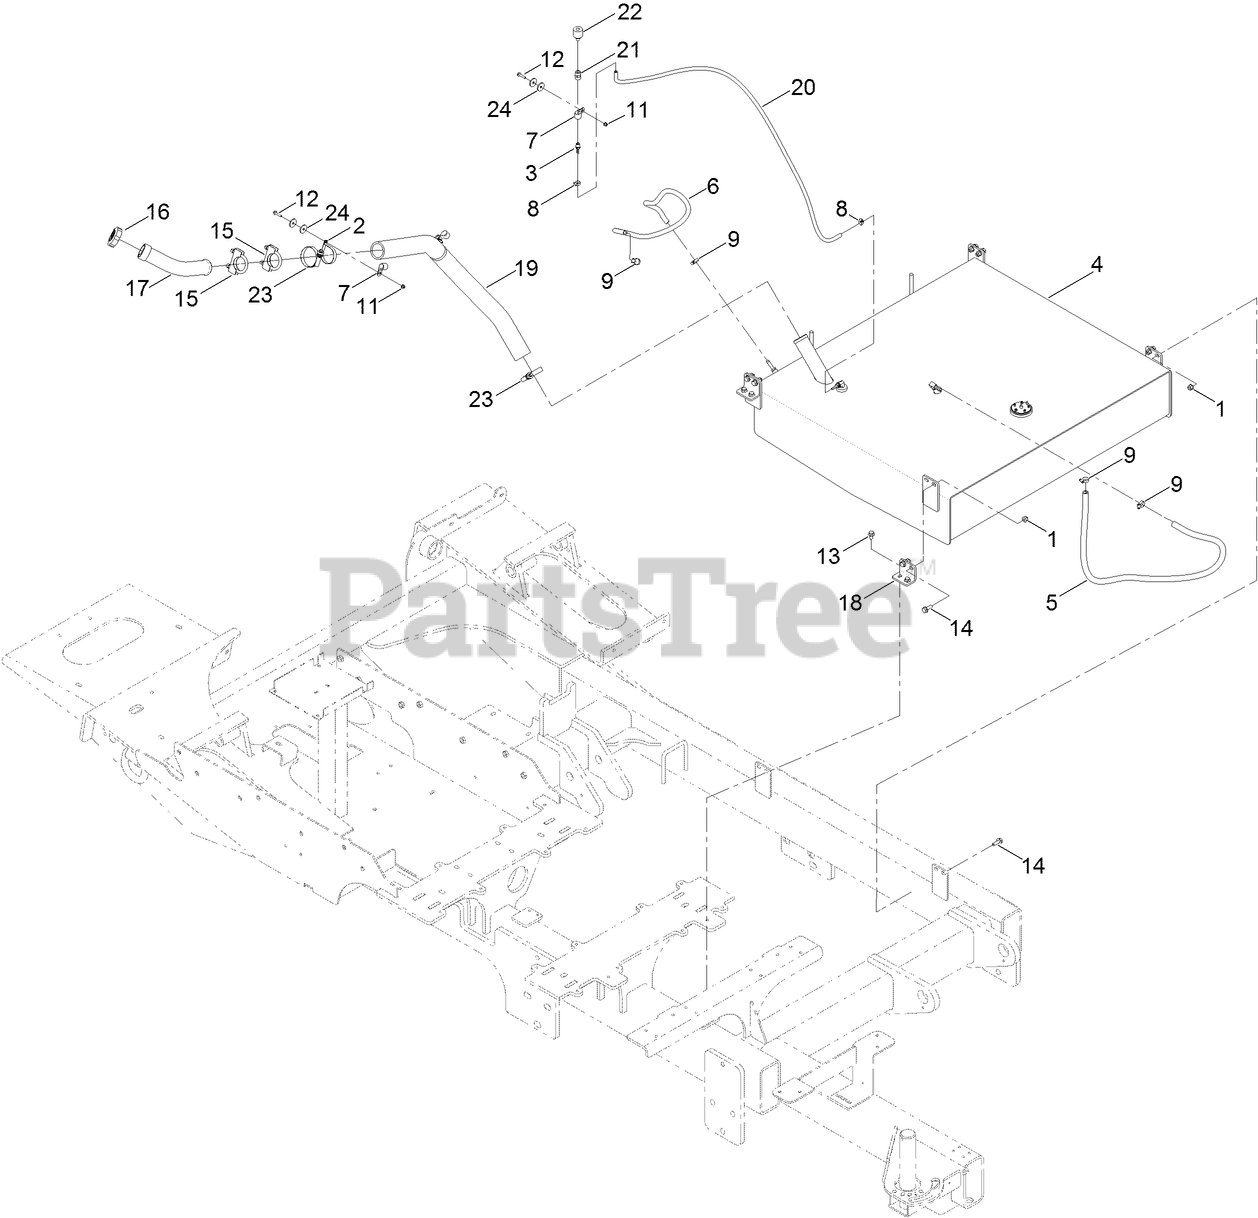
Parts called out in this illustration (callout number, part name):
1	NUT-LOCK, NI
2	R-Clamp
3	FITTING-STRAIGHT
4	FUEL TANK ASM
5	HOSE-FUEL
6	HOSE-FUEL
7	CLAMP-R
8	CLAMP-WORM
9	CLAMP-HOSE
11	NUT-FLANGE, NI
12	SCREW-HHF
13	SCREW-HHF
14	SCREW-HHF
15	BOLT-U, CLAMP
16	CAP-FUEL (W/LOCK)
17	NECK-FILLER - FUEL
18	PLATE-MOUNTING, TANK
19	HOSE-FUEL, TANK FILL
20	HOSE-FUEL
21	COUPLING-PIPE (NPTF)
22	BREATHER
23	Clamp-Hose
24	Washer-Flat
